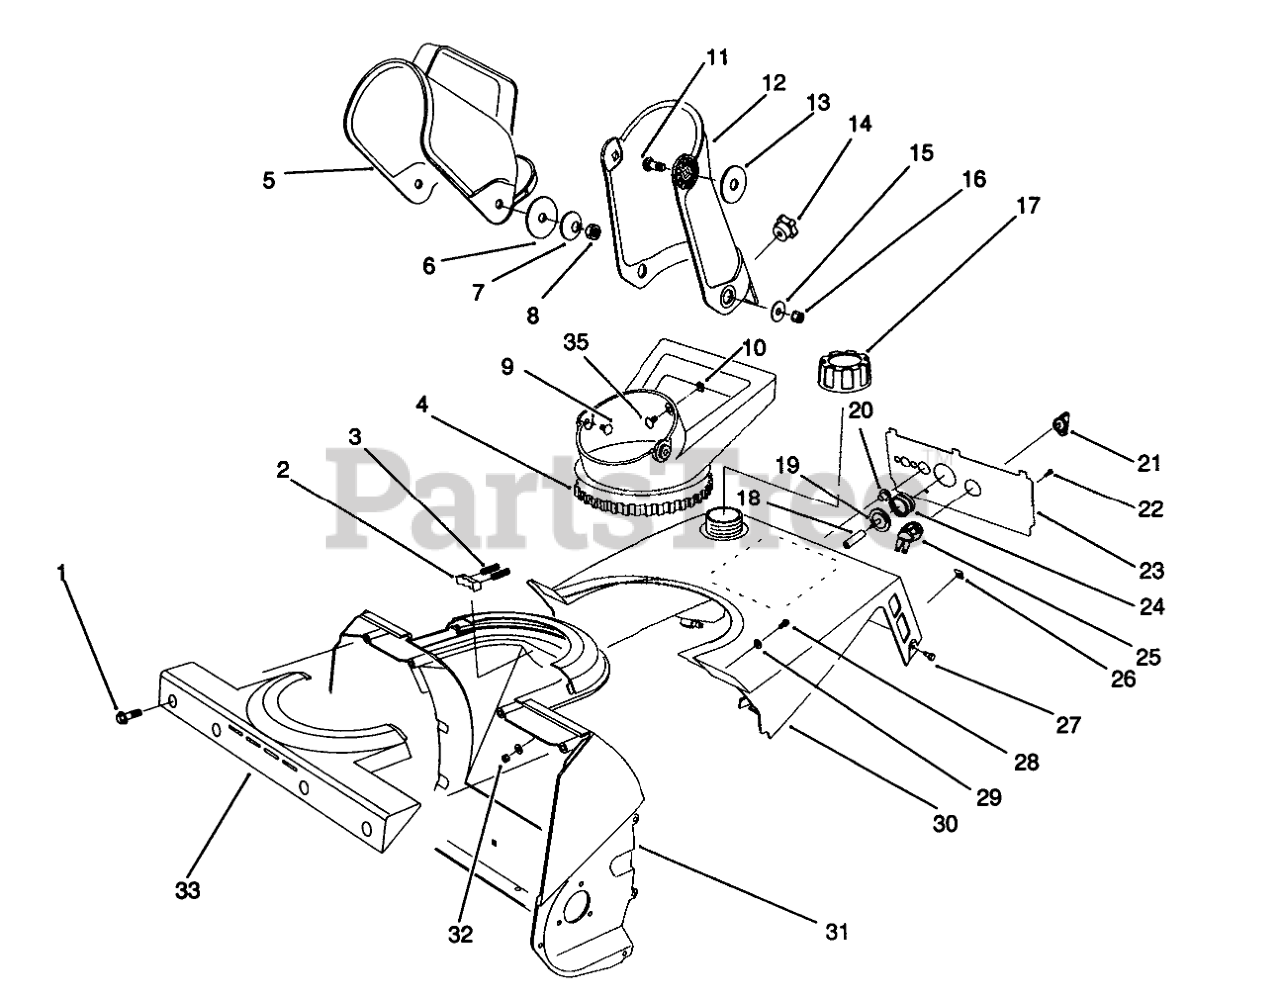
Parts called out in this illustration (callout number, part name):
1	SCREW-PLASTIC
2	DETENT-CHUTE
3	SPRING-COMPRESSION
4	HANDLE-CHUTE
5	DEFLECTOR-CHUTE
6	WASHER-FLAT
7	WASHER-BELLEVILLE
8	NUT-LOCK, NI
9	SCREW-HH
10	PUSHNUT-RETAINER, BOLT
11	BOLT-CARR
12	CHUTE
13	Washer-Rubber
14	KNOB-CHUTE
15	WASHER-FLAT
16	NUT-LOCK, NI
17	CAP-FUEL ASM
18	HOSE-PRIMER
19	BODY-PRIMER
20	GUIDE-ROPE, STARTER
21	KEY-IGNITION
22	SCREW-SHWH, THREAD FORMING
23	CNTRL PNL/SILK SCRN
24	BULB-PRIMER
25	SWITCH
27	SCREW-THREAD FORMING
28	SCREW-PPH
29	WASHER-FLAT
30	Shroud-Upper
30	Shroud-Upper (Model 38175)
31	HOUSING
32	NUT-LOCK, NI
33	RETAINER-CHUTE
34	SCREW-CARR
